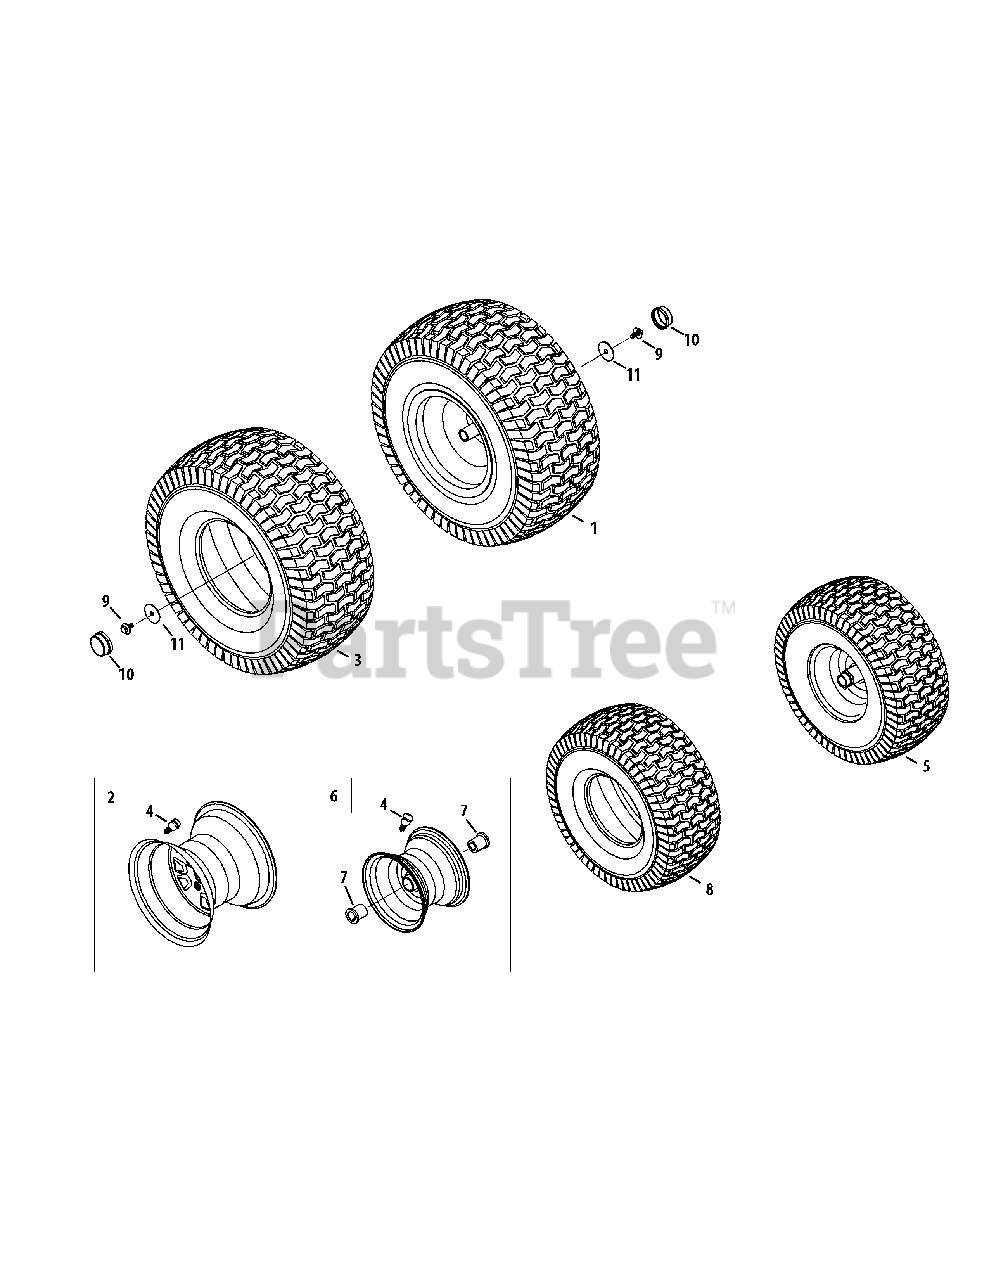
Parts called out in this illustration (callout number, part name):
1	Wheel, Complete, 20 x 8 x 8
2	Rim Ass’y, 8.0 x 7.0 x .750 ID
3	Tire, 20 x 8 x 8 Sq Shoulder
4	Valve, Tubeless Air
5	Wheel, Complete, 15 x 6 x 6
6	Rim Ass’y, 6.0 x 4.5, Flnge Bearings
7	Bearing, Flange, .760 ID
8	Tire, 15 x 6 x 6 Sq Shoulder
9	Screw, 5/16-24 x .850
10	Hub Cap
11	Flat Washer, .350 x 1.59 x .062
